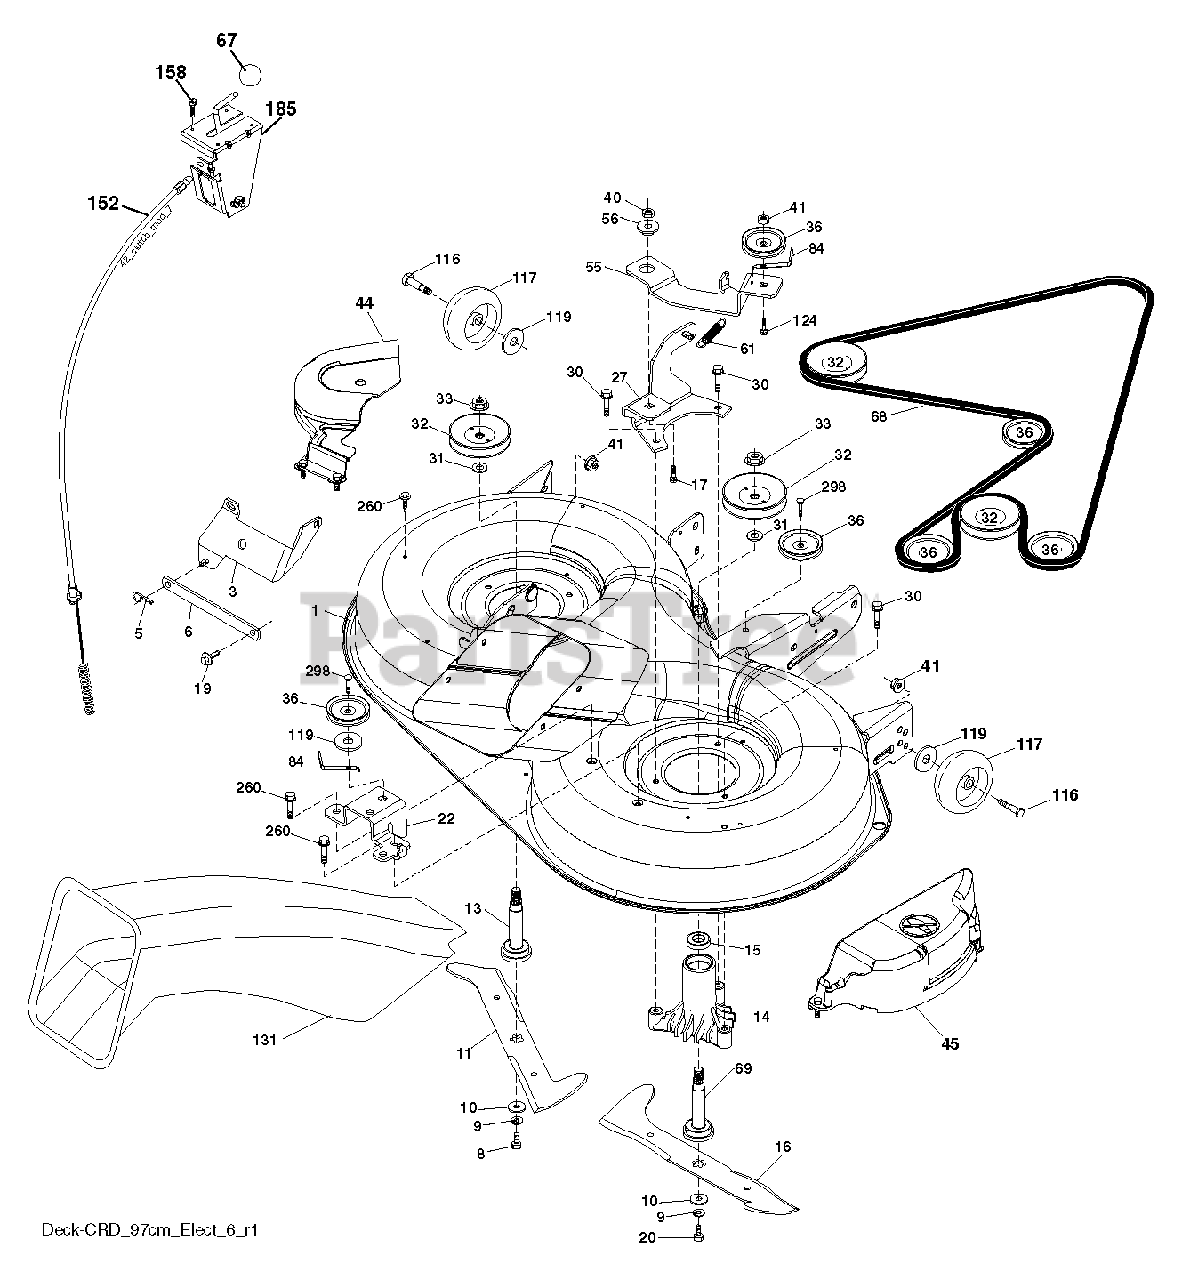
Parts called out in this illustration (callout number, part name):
3	BRACKET.ASM.BAR.SWAY.CHASS
5	RETAINER-SPRNG RB
6	BAR SWAY
9	LOCKWASHER
10	WASHER.BLADE
11	BLADE.3N1.LH.CRD.97
13	SHAFT ASM VENT
14	HSG MANDREL
16	BLADE.3N1.RH.CRD.97
17	BOLT.3/8-14X1.25
19	BOLT SHD 5/16-18
22	BRACKET.SUPT.IDLER.REAR.RH
27	BRACKET.ASM.SUSP.REAR.RH.
30	SCREW, WASHER HEAD
31	WASHER.SPACER.MANDREL
32	PULLEY MANDREL
33	NUT.FLANGE.LOCK.TOP
36	PULLEY.IDLER.4.25
40	LOCKNUT
41	NUT LOCK FLG 3/8-16 UNC
56	SPACER.RETAINER.MOWER
67	KNOB T (3/8 HOLE)
68	BELT.DRIVE.CRD.97.2010
69	SHAFT.ASM.W/LWR.BRG.RH.THREAD
84	KEEPER, BELT IDLER
116	BOLT.SHOULDER.3/8-16X3-5/8
117	WHEEL. GUAGE RALLY
124	BOLT.3/8-16X1.50
131	CHUTE BAGGER
158	SCREW
185	HEAD ASM. CABLE CLUTCH
260	SCREW 3/8-16X1/2
298	SCREW LT
